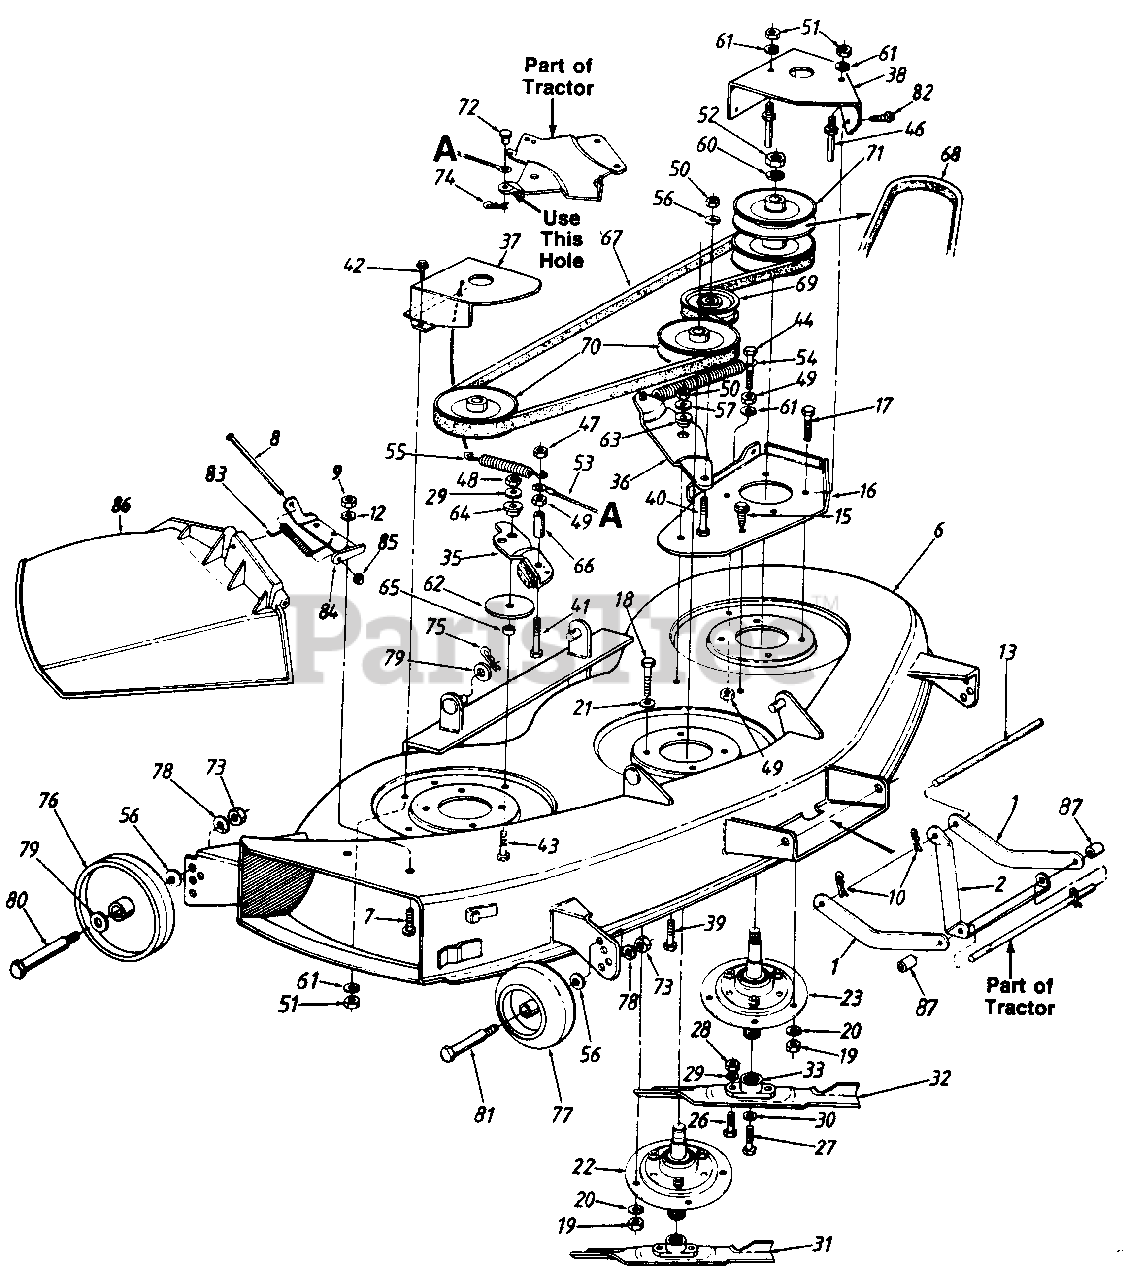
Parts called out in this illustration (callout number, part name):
7	Truss Mach. Scr. 1/4-20 x .75"
8	Hinge Pin
9	Hex Jam Nut 1/4-20 Thd.
10	Part Specification Not Listed
12	Bell-Wash. 1/4" I.D.
13	Deck Connecting Rod
15	Hex TT-Tap Scr. 5/16-18 x .62"
18	Hex Bolt 5/16-24 x .75" Lg.
19	Hex Nut 5/16-24 Thd.
20	L-Wash. 5/16" I.D.
21	Bell-Wash. 5/16" I.D.
22	Spindle Ass'y.
23	Spindle Ass'y.
26	Hex Bolt 5/16-24 x 1.0" Lg.
27	Hex Cl-Bolt 3/8-24 x .88" Lg.
28	Hex Nut 5/16-24 Thd.
29	L-Wash. 5/16" I.D.
30	L-Wash. 3/8" I.D. H.D.
31	High Lift Blade 14.88" Lg.
32	High Lift Blade 16.28" Lg.
33	Blade Adapter
35	Deck Brake Brkt. Assy.
36	Idler Bracket
40	Hex Bolt 3/8-24 x 1.5" Lg.
41	Hex Bolt 1/4-28 x 1.75" Lg.
42	Hex Wash. Hd. Tap-Scr. 1/4-20 x .5" Lg.
43	Hex Bolt 5/16-24 x 1.25" Lg. (Grade 5)
44	Hex Bolt 1/4-28 x 1.5" Lg.
46	Belt Guard Pin 1/4" Dia.
47	Hex Cent. L-Nut 1/4-28 Thd.
48	Hex Nut 5/16-24 Thd.
49	Hex Nut 1/4-28 Thd.
50	Hex Nut 3/8-24 Thd.
51	Hex Nut 1/4-20 Thd.
52	Hex Jam Nut 5/8-18 Thd.
53	Brake Cable Ass'y.
54	Extension Spring 6.17" Lg.
55	Extension Spring 3.97" Lg.
56	Bell-Wash. .38" I.D. x .88" O.D.
57	Bell-Wash. .39" I.D. x 1.13" O.D.
60	Bell-Wash. 5/8" I.D. x 1.25" O.D.
61	L-Wash. 1/4" I.D.
62	Fl-Wash. 5/16" I.D. x 3" O.D.
63	Shld. Spacer .625" I.D.
64	Shld. Spacer
65	Spacer .34" I.D.
66	Spacer .326" I.D.
67	V-Belt
68	V-Belt
69	Fl-Idler w/Flanges 3.5" O.D.
70	Pulley 5.0" Dia.
71	Pulley 5 on Dia.
72	Clevis Pin 1/4" Dia. x .53" Lg.
73	Hex Nut 3/8-16 Thd.
74	Intern. Cotter Pin 5/16" Dia.
75	Intern. Cotter Pin 3/8 Dia.
76	Deck Wheel 5" Dia.
77	Deck Wheel w/lnsert 5" Dia.
78	L-Wash. 3/8" I.D.
79	Fl-Wash. .531" I.D.
80	Shoulder Bolt .498" Dia. x 1.64" Lg.
81	Shoulder Bolt
82	Hex Wash. Hd. Tap-Scr. 1/4-20 x .38" Lg.
83	Torsion Spring
84	Hinge Mtg. Brkt.
85	Push Nut
86	Chute Ass'y. Comp.
87	Spacer 5/8" I.D. x 7/8" O.D.
17258-0648	Deck Belt Cover, 46" Black - TECH GRAY (0648)
17258-0665	COVER:BELT:DECK 46 - YARDMAN GREEN (0665)
